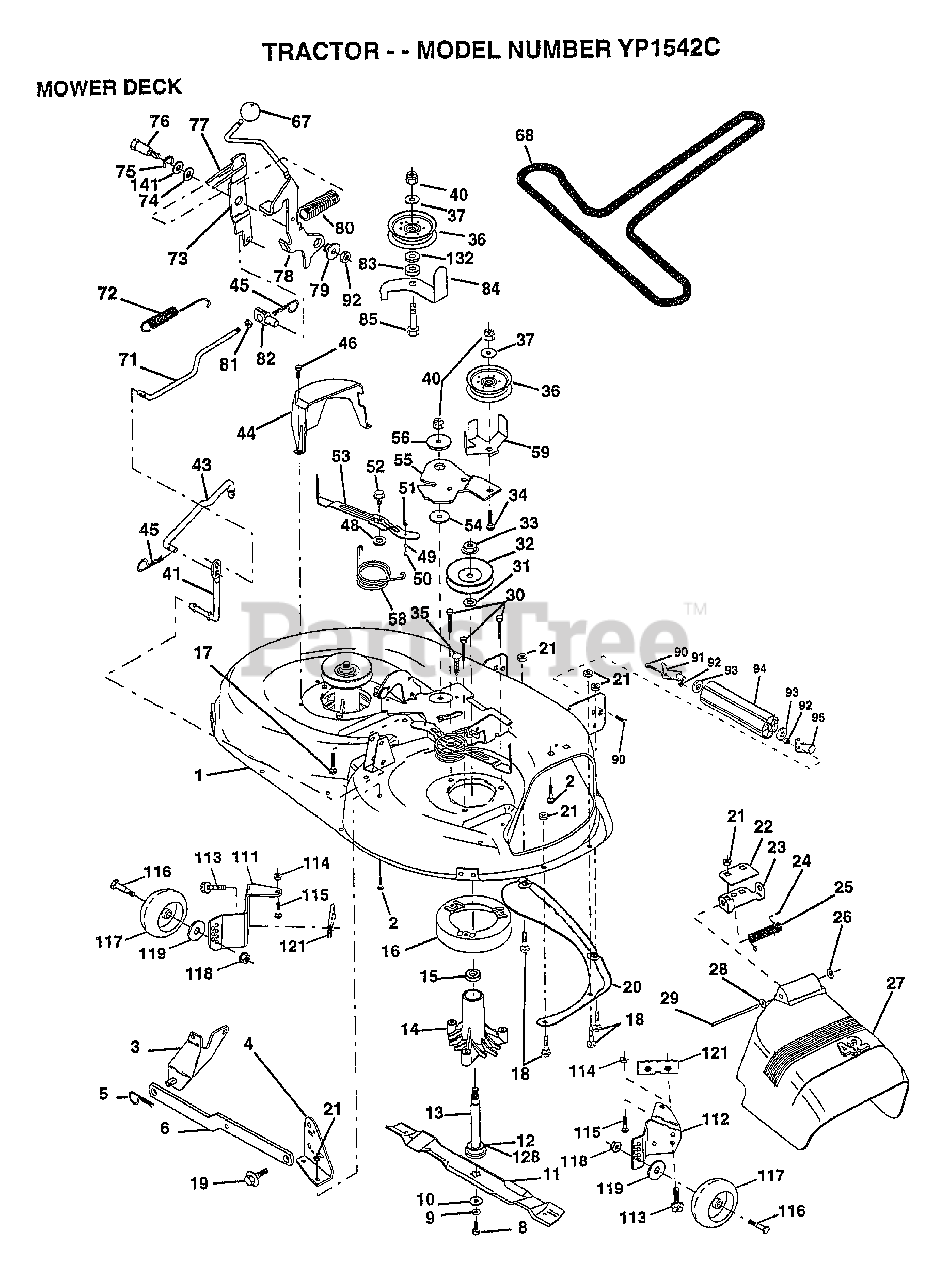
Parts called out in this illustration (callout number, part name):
1	"HOUSING ASSY.42"""
2	BOLT
3	BRKT ASM SWAY BAR
4	BRKT DECK SW BAR
8	BLADE BOLT
10	WASHER.HARD.BLADE
11	"BLADE.42"" HIPERF"
12	BEARING.BALL
14	HSG ASM MANDREL
15	BEARING
16	STRIPPER RND MWR
17	BOLT RDHD 3/8-16
18	BOLT
19	BOLT SHD 5/16-18
20	BAFFLE VORTEX 42
22	STIFFENER BRKT
23	DEFLECTOR BRKT
24	CAP-SLEEVE LT
25	SPRING TORSION
26	NUT PUSH M
27	DEFLECTOR.SHIELD
28	WASHER
29	HINGE ROD
30	"SCREW-THD ROLL,WA"
31	WASHER
32	PULLEY.MANDREL.42
34	BOLT
35	XMAS TREE FASTNER
36	FLAT IDLER PULLEY
37	WASHER
41	PIVOT ROD
43	ROD CLUTCH W/NIBS
44	GUARD MAND LH BLK
45	RETAINER M
46	SCREW.1/4-20X5/8
48	HARD SMALL WASHER
49	ROLLER ASM-CAM
50	SHOULDER BOLT
51	LOCKNUT
52	BOLT.SHLD.5/16-18
53	BRAKE PAD ARM ASM
54	HARDENED WASHER
55	ARM-IDLER
56	SPACER RETAINER
58	SPRING TORSN BRAK
59	GUARD IDLER TUV
67	KNOB.RD.7/16-14
68	BELT.V.T-PATH
71	ROD CLUTCH 38/42
72	RETURN SPRING
73	CLUTCH ARM SECOND
74	WASHER
75	RING
76	SHOULDER BOLT
77	SPRING KEEPER
78	LEVER.ASM.CLUTCH
79	BUSHING
80	SPRING.CLUTCH.MWR
81	NUT
82	TRUNION ADJ
83	WASHER
84	"KEEPER-BELT,FIXED"
85	BOLT
90	BOLT
92	NUT
93	WASHER
111	BRACKET.GWHL.LH.
112	BRACKET.GWHL.RH.
113	SCREW
116	BOLT M
117	WHEEL.GUAGE
118	LOCKNUT
119	WASHER
121	BRACKET.EXTRD.GWL
128	WASHER.FELT.
132	WASHER GT
141	WASHER .T
